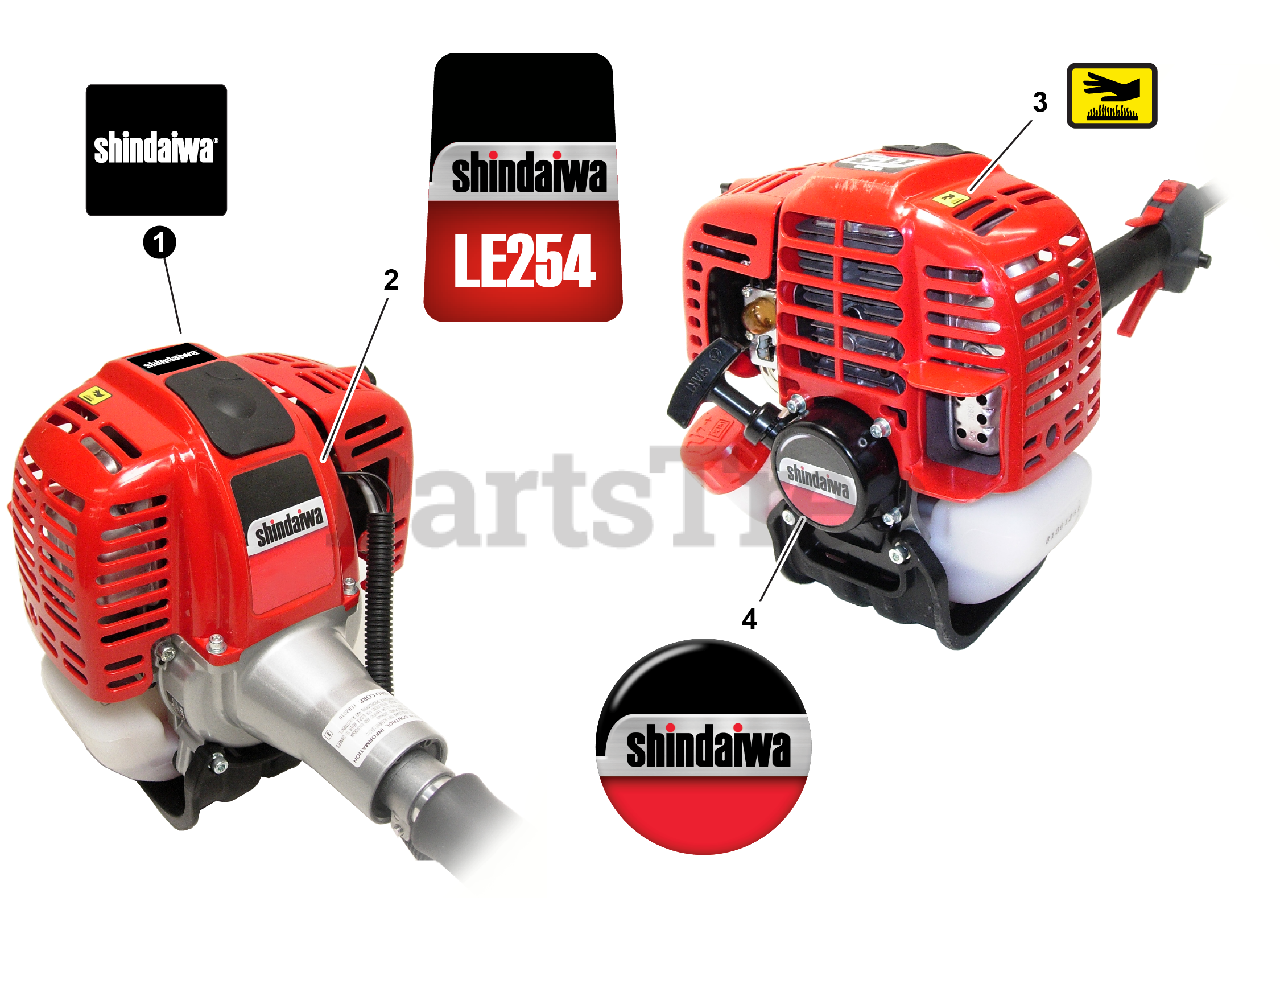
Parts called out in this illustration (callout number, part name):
1	LABEL, shindaiwa
2	LABEL, LE-254
3	LABEL, CAUTION - HOT
4	LABEL, RECOIL STARTER
